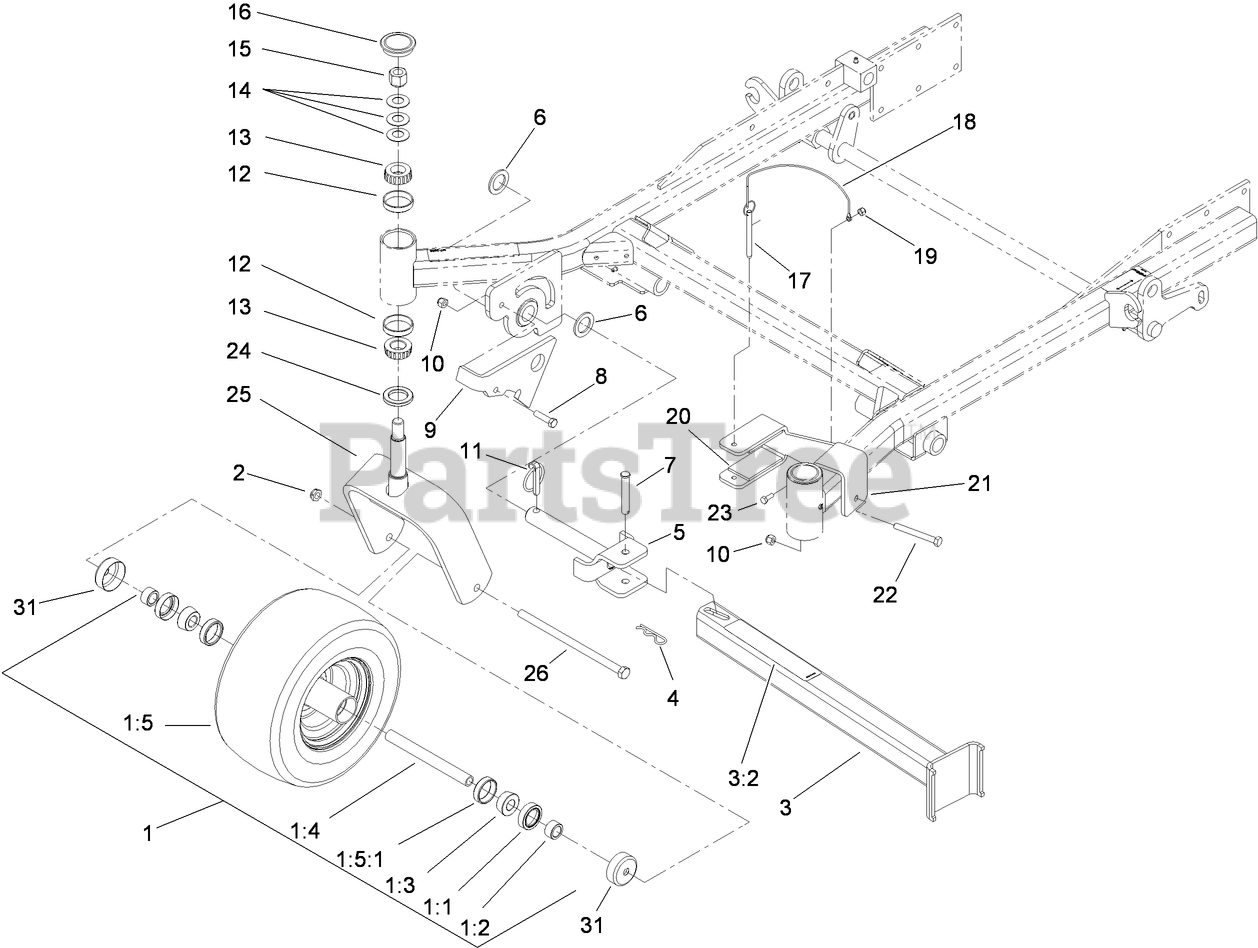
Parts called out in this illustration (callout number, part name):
1	WHEEL AND TIRE ASM
1:1	BEARING-CONE, TAPER
1:2	SEAL-CASTER
1:3	SPACER-NUT
1:4	AXLE-CASTER
1:5	WHEEL AND TIRE ASM
1:5:1	BEARING-CUP
2	NUT-LOCK, NI
3	Leg ASM
3:2	DECAL-Z STAND
4	PIN-HAIR
5	PIN-PIVOT
6	WASHER-THRUST
7	PIN-CLEVIS
8	SCREW-HH
9	BRACKET-LATCH
10	NUT-LOCK, NI
11	PIN-LYNCH
12	BEARING-CUP, TAPERED
13	BEARING-CONE, TAPERED
14	WASHER-BELLVILLE
15	NUT-LOCK, NI
16	CAP-GREASE
17	PIN-HITCH, COTTERLESS
18	LANYARD-NYLON
19	NUT-LOCK, NI
20	Cushion-Rubber
21	BRACKET-CRADLE
22	SCREW-HH
23	SCREW-HH
24	SEAL-GREASE
25	CASTER-FORK
26	Screw-HH
31	GUARD-SEAL
